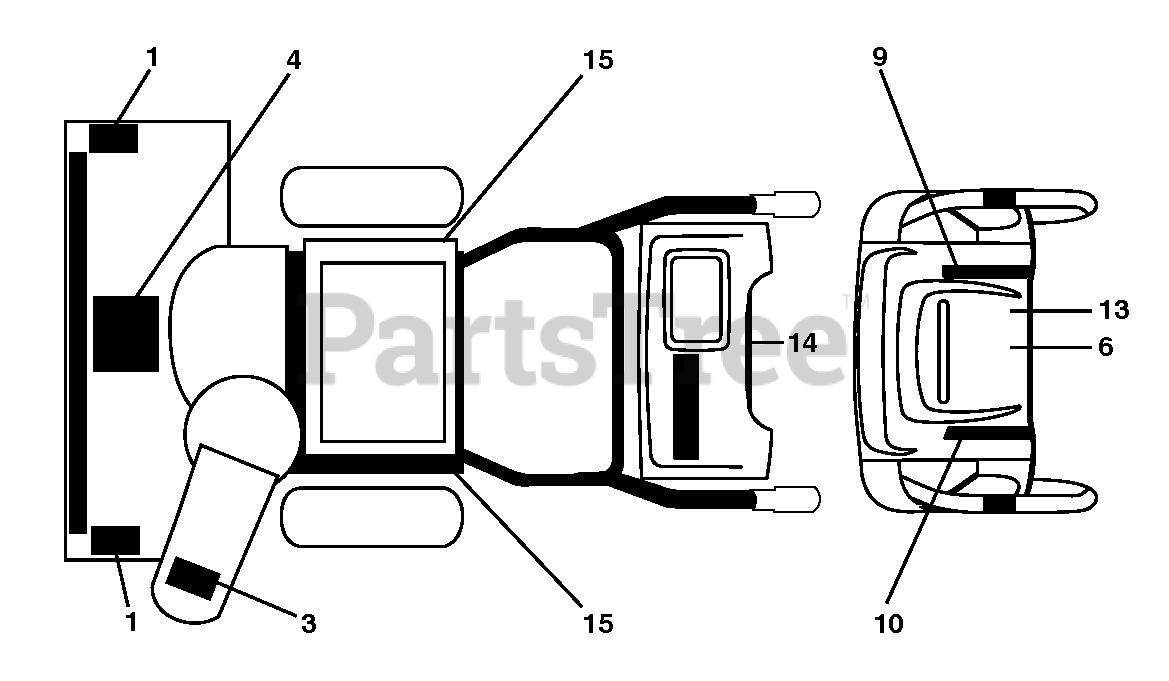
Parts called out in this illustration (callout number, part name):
1	DECAL.AUGER.SAFETY.
3	DECAL.CHUTE.SAFETY.
4	DECAL.AUGER."
9	DECAL CONSOLE DECAL DECAL.SNOW
10	DECAL CONSOLE DECAL DECAL.SNOW
13	DECAL.CONSOLE.HAND.WARMER
14	DECAL.NOISE.LEVEL.105DB/CE.EAC
15	DECAL.BELT.GUARD.
